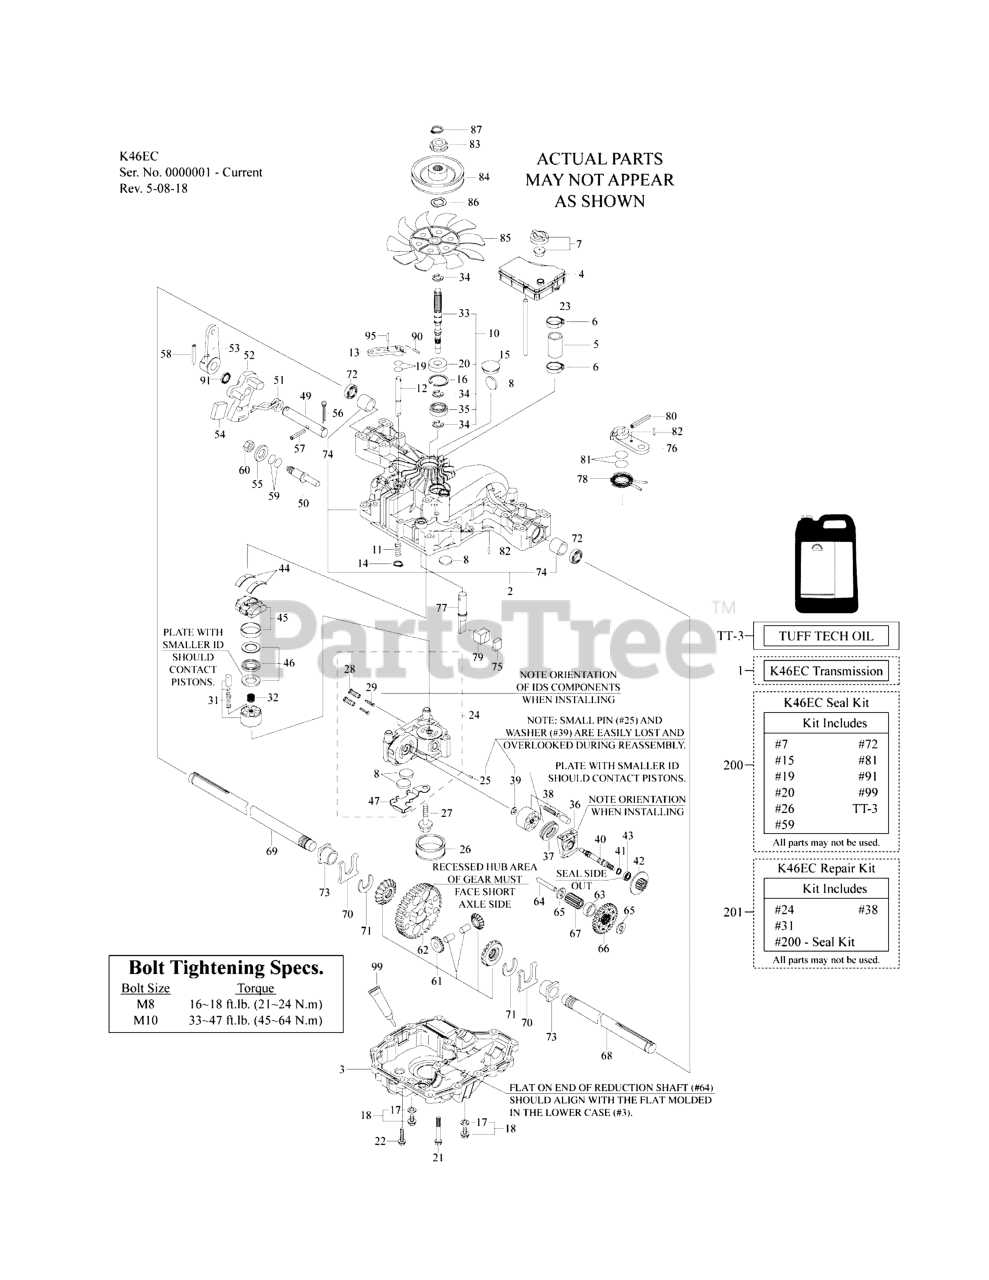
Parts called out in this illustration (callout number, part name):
1	TRANSMISSION, Tuff Torq K46EC
2	KIT, Upper Case
3	LOWER CASE
5	TUBE
6	COBRA CLAMP
7	VENT VALVE 15
8	MAGNET
9	* MAGNET HOLDER
10	* KIT, Pump Shaft/Bearing
12	BYPASS SHAFT A
13	LEVER, Bypass
14	RING, Snap, 10
15	SEALING CAP 30
16	RING, Snap, C 35
17	SEAL WASHER 8
18	* KIT, Drain Bolt
19	0-RING, 1A P10A
20	SEAL TC 153507
22	SCREW, Tapping, 8 * 30
23	TANK SUPPORT
24	* CENTER CASE K W/ 1.2 FILTER IDS KIT
25	PIN, 3 * 9.8
27	BOLT, 10 * 75
29	* IDS SPRING
31	*KIT, Cylinder Block (Pump)
33	PUMP SHAFT
34	E-RING 15
35	BEARING, 6202C3
36	MOTOR HOUSING
38	KIT, Cylinder Block
39	WASHER, 12 * 24 * 1
40	MOTOR SHAFT
41	RING, Snap, S15
42	BRAKE DISC/MOTOR GEAR (10T)
44	THRUST METAL
45	* SWASH PLATE CMP
46	THRUST BEARING K81105
47	MAGNET HOLDER
49	* CONTROL SHAFT
50	* FULCRUM
51	* SPRING, Torsion
52	* CONTROL ARM A
53	CONTROL LEVER C
54	* JERKY PLATE
55	WASHER, 12
56	COTTER PIN, 1/8 * 3/4
57	SPRING PIN 6 * 36
58	ROLL PIN 6 * 40
59	O-RING 1A P14
60	NUT 12
61	* KIT, Diff Gear
63	* FINAL PINION COLLAR
64	* REDUCTION SHAFT
65	WASHER, 12 * 32 * 3.2
66	REDUCTION GEAR (38T)
68	AXLE SHAFT, Left
69	AXLE SHAFT, Right
70	THRUST WASHER
71	RING 17
72	SEAL 19 * 32 * 8
73	BUSHING, 19 * 25
75	BRAKE SHOE
76	BRAKE LEVER
77	* BRAKE SHAFT
78	* SPRING, Brake Return
79	BRAKE ACTUATOR
80	SPRING PIN 5 * 32
81	O-RING 1A P12
82	SPRING PIN 4 * 16
83	SPLINE COLLAR
84	PULLEY D
85	FAN, White
86	WASHER, Wave
87	RING, Snap
91	OIL SEAL 16 * 22 * .03
99	SEALANT
200	* K46 & T40 SEAL KIT (ALL MODELS)
